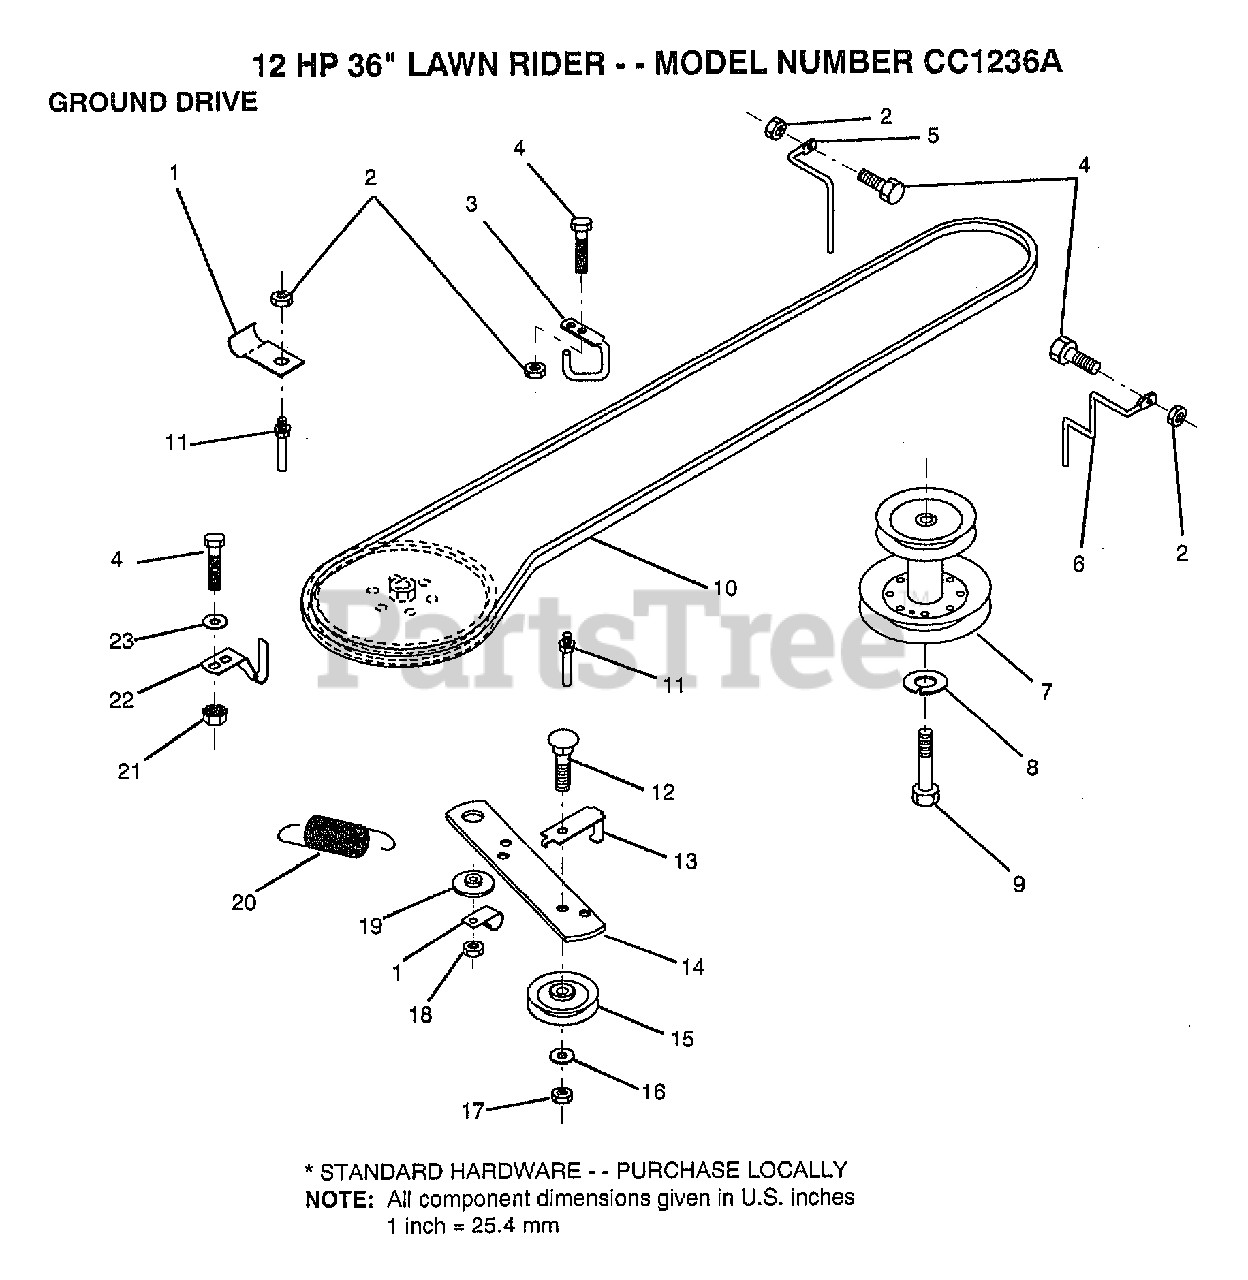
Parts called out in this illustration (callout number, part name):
1	"CLIP,INSULATOR"
3	"KEEPER,FRA DR BEL"
4	BOLT
8	LOCKWASHER
9	BOLT
10	BELT
11	"KEEPER,DRIVE BELT"
12	BOLT
13	"KEEP,IDLER DR BEL"
16	WASHER
17	LOCKNUT
19	SPACER RETAINER
22	"KEEPER,DR BELT "
23	WASHER
